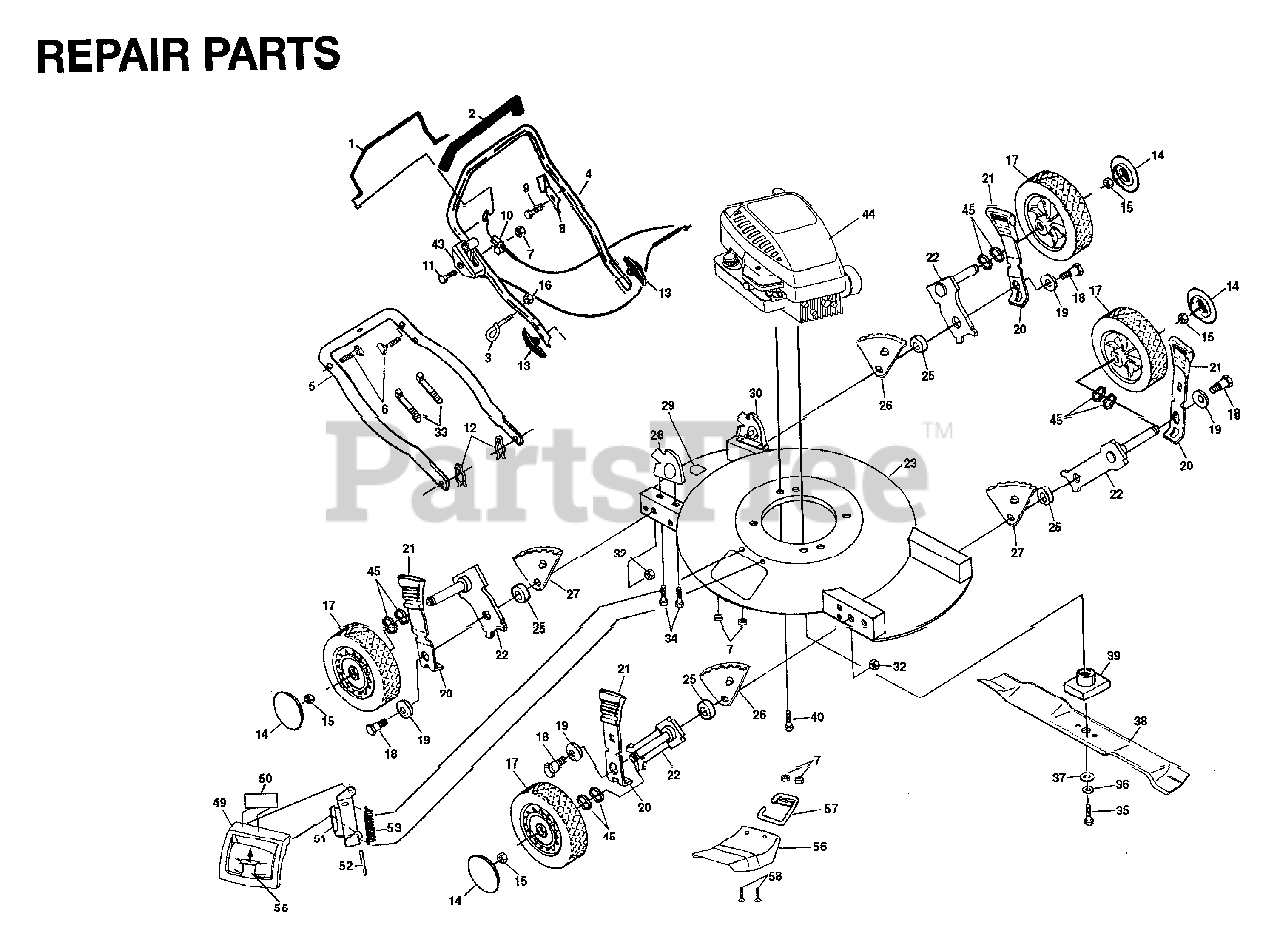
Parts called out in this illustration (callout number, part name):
1	CONTROL BAR/BLACK
2	HANDLE GRIP
3	ROPE GUIDE
4	UPPER HANDLE
6	HANDLE BOLT
7	NUT.CROWNLOCK.1/4
8	BRACKET UPSTOP
10	ENGINE ZONE CONTROL CABLE
11	SCREW 1/4-20 X 2.12
12	HAIRPIN COTTER
13	HANDLE KNOB
14	HUB CAP PM
15	HEX FLANGE LOCKNT
16	NUT.CROWNLOCK.1/4
18	BOLT
19	BELLEVILLE WASHER
20	SELECTOR SPRING
21	SELECTOR KNOB
22	AXLE ARM
25	RP SPACER HT ADJ
28	HDLE BRKT ASSY RH
29	DECAL MOWER CUT/FINGER
30	HDLE BRKT ASSY LH
32	LOCKNUT
33	CLIP CABLE SNAP
34	SCREW
35	SCREW, HEX HD 3/8-24 X 1-3/8
36	LOCKWASHER
37	WASHER,HARDEN
38	BLADE.20.MULCH.(50DK,6020MD)
39	RP BLADE ADAPTOR
40	BOLT
43	THROTTLE CONTROL
45	WAVE WASHER
49	MULCHER DOOR
51	BRACKET PM
53	SPRING PM
55	DOOR LATCH
56	MULCHER DEFLECTOR
57	BRACKET.CHUTE.MTG
